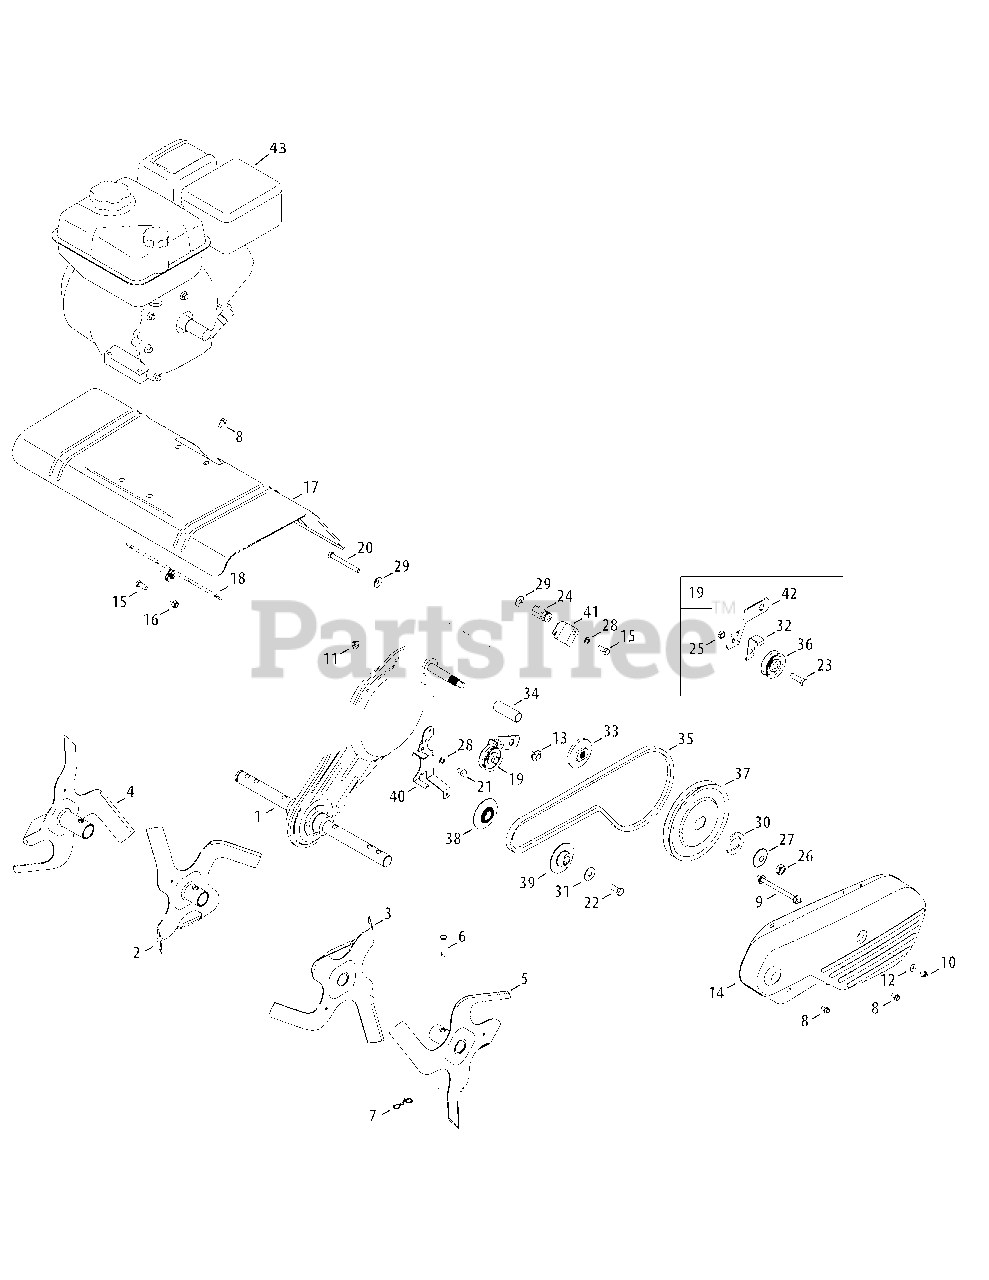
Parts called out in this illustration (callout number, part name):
1	Chain Case Assembly
2	Inner Tine Assembly, RH
3	Inner Tine Assembly, LH
4	Outer Tine Assembly, RH
5	Outer Tine Assembly, LH
6	Clevis Pin, .375 x 1.75
7	Bow Tie Cotter Pin
8	Screw, 1/4-20 x 0.500
9	Bolt, Belt Cover
10	Nut, 1/4-28, Lock
11	Nut, 5/16-18, Flange Lock
12	Flat Washer, .271 x .630 x .065
13	Shoulder Screw, .560 x .165 5/16-18
14	Belt Cover
15	Hex Head Screw, 5/16-18 x .75
16	Nut, 5/16-18, Flange Lock
17	Tine Shield
18	Bracket, Tine Shield
19	Idler Bracket Assembly
20	Hex Head Screw, 5/16-18 x 3.00
21	Hex Head Screw, 5/16-24 x .625
22	Hex Head Screw, 3/8-24 x 1.00
23	Hex Head Screw, 3/8-16 x 1.25
24	Hex Nut, 5/16-18
25	Jamlock Nut, 3/8-16
26	Nut, 1/2-20, Jam
27	Washer, .531 x 1.62 x .045
28	Lock Washer, 5/16
29	Bell Washer, .340 x .872 x .060
30	Flat Washer, 1.26 x 1.87 x .150
31	Bell Washer, .396 x 1.140 x .095
32	Belt Keeper
33	Pulley Adaptor
34	Spacer, .64 ID x 2.4
35	Belt, 4L x 41.9 LG
36	Pulley 1.88 OD
37	Pulley 6.00 OD
38	Inner Engine Pulley
39	Outer Engine Pulley
40	Belt Keeper Bracket
41	Cable Guide Bracket
42	Idler Bracket
43	Replacement Engine
